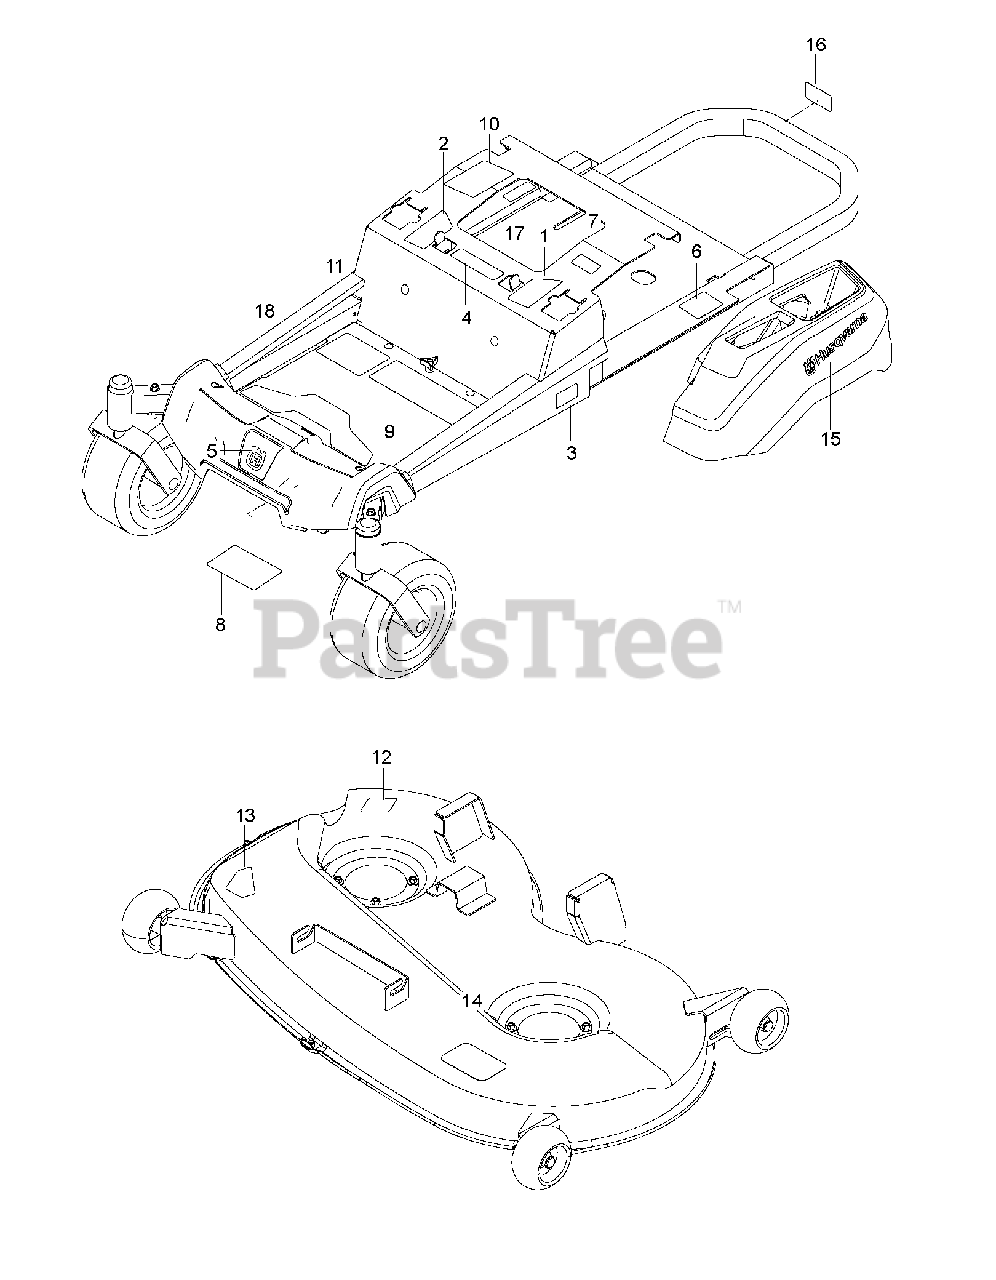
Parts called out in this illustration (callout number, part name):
1	DECAL.ZTR.RZ.THRTL/PRKBRK.V2.L
2	DECAL.ZTR.RZ.THRTL/PRKBRK.V2.R
3	DECAL.ZTR.SIDERAIL.Z246.HUSQ
4	EURO DECAL-BATTERY WARNIN6
5	DECAL.BADGE.55MM.CROWNH.HUSQ
6	DECAL, DO NOT TOW
7	DECAL, EXITING MOWER
8	DECAL, SERVICE
9	DECAL.ZTR.WARNING.SMARTIGNITIN
10	DECAL, CUSTOMER RESPNSIBILITY
11	DECAL.ZTR.STARTINS.READYSTART
12	DECAL.DECK.6MIL./DEF.SHLD.WARN
13	DECAL, DECK DEFLECTOR, WARNING
14	DECAL, BELT ROUTING
15	DECAL.HUSQVARNA.210MM
16	DECAL, PROP. 65
17	DECAL, WARNING SPARK ARRESTOR
18	PAD.RZ.FOOTREST.PLATE
